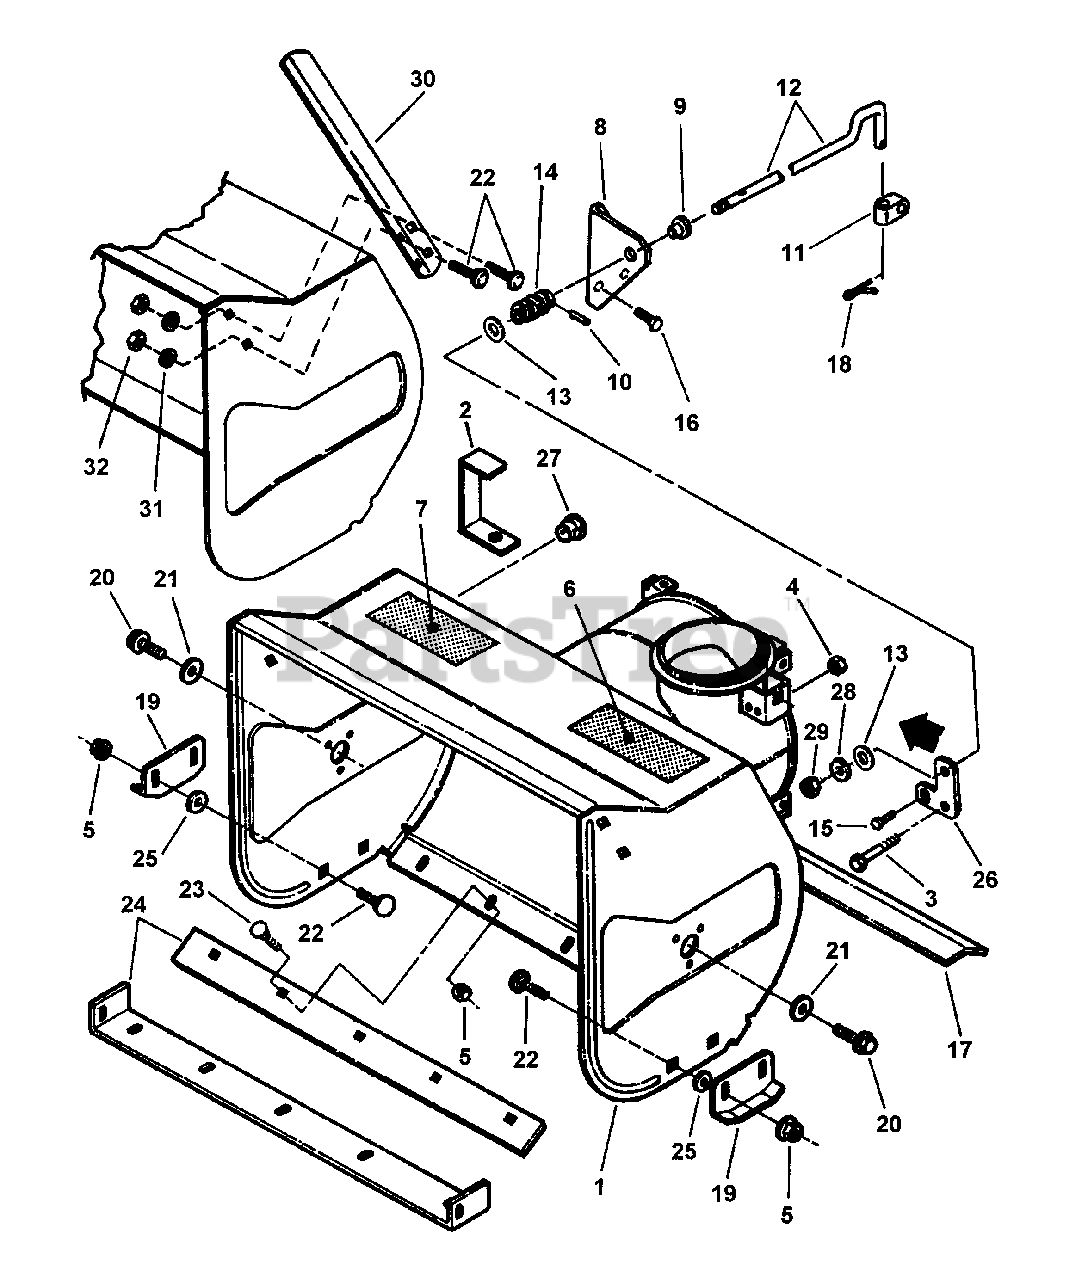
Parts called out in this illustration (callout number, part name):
1	ASSEMBLY, 24" Blower
2	GUIDE, Cable
3	SCREW, 5/16-24 x 3/4" Hex Head Cap, Grade 5
4	NUT, 5/16-24 Hex Center Lock, Grade B
5	NUT, 5/16-18 Hex Flange Lock, Grade 5
6	DECAL, Danger Rotating Auger
7	DECAL, Heavy Duty Snow
8	BRACKET, Worm Shaft Support
9	BUSHING
10	PIN, 1/8 x 3/4" Roll
11	CONNECTOR
12	SHAFT, Worm (3/8-16 threaded)
13	WASHER, 13/32 Spring
14	WORM
15	SCREW, 1/4-20 x 1/2" Hex Washer Self-Tap
16	SCREW, 5/16-18 x 1/2" Hex Washer Self-Tap
17	BAR, Stiffener
18	PIN, 3/32 x 3/4" Cotter
19	SHOE, Skid
20	SCREW, 3/8-16 x 1" Hex Washer Self-Tap
21	WASHER, 3/8" Flat
22	BOLT, 5/16-18 x 3/4" Short Neck Carriage, Grade 5
23	BOLT, 5/16-18 x 1/2" Short Neck Carriage, Grade 5
24	BLADE, Scraper
25	WASHER, 5/16 Flat
26	BRACKET, Worm
27	PLUG, Dome 5/16"
28	WASHER, 3/8" Flat
29	NUT, 3/8-16 Hex Center Lock, Grade 5 or B
30	DRIFT CUTTER
31	WASHER, 5/16 Split Lock
32	NUT, 5/16-18 Hex
